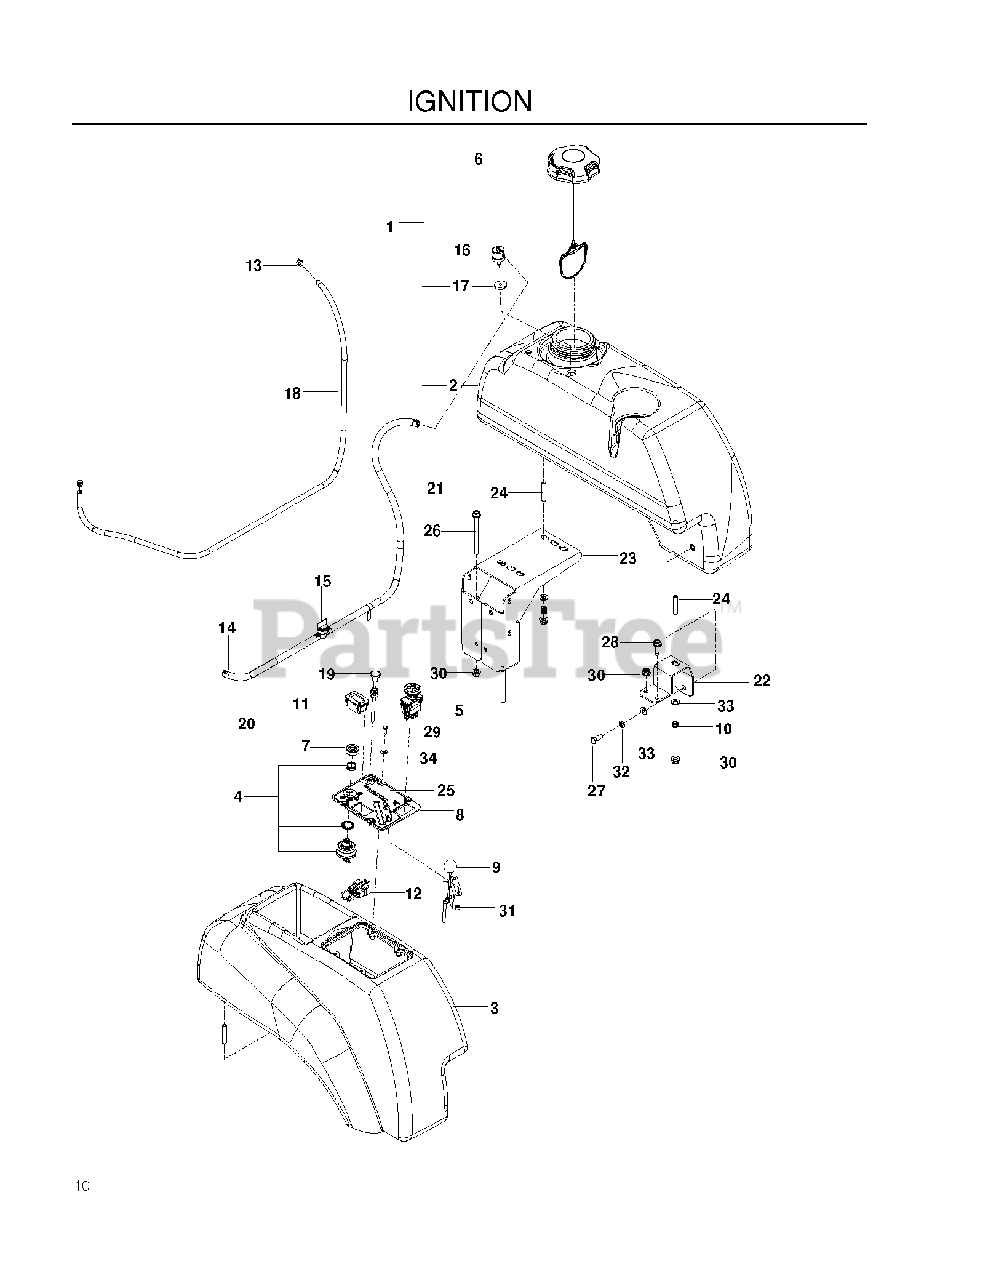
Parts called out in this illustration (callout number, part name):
1	ASSEMBLY, LT TANK, EPA-BLK
3	CONSOLE, RT-BLK
4	SWITCH, IGNITION, INDAK
5	SWITCH, PTO 10 AMP
6	CAP, FUEL
8	PLATE, CONSOLE, BLK
9	THROTTLE CONTROL W/BALL KNOB
11	HOUR METER
12	PLUG, TIMER
13	CLAMP, HOSE
14	HOSE CLAMP
15	FUEL VALVE
16	VALVE.FUEL.CHECK
17	GROMMET, CHECK VALVE
18	HOSE, VAPOR 3/16 X 48"
19	CABLE, CHOKE KAWASAKI
20	HOSE, FUEL .25 ID X 26"
21	GAS LINE 10"
22	SUPPORT, TANK, BLK
23	MOUNT, TANK, ZT BLK
24	STUD, 5/16C
26	HHFS 5/16-18 X 3 3/4
27	HCS 5/16C X 3/4
29	HCS #10-24 X 1/2
30	5/16-18 NYLOC FLANGE NUT
31	NUT 10-24 NYLOC
32	WASHER 5/16 LOCK
33	FLAT WASHER 5/16 SAE
34	WASHER #10
